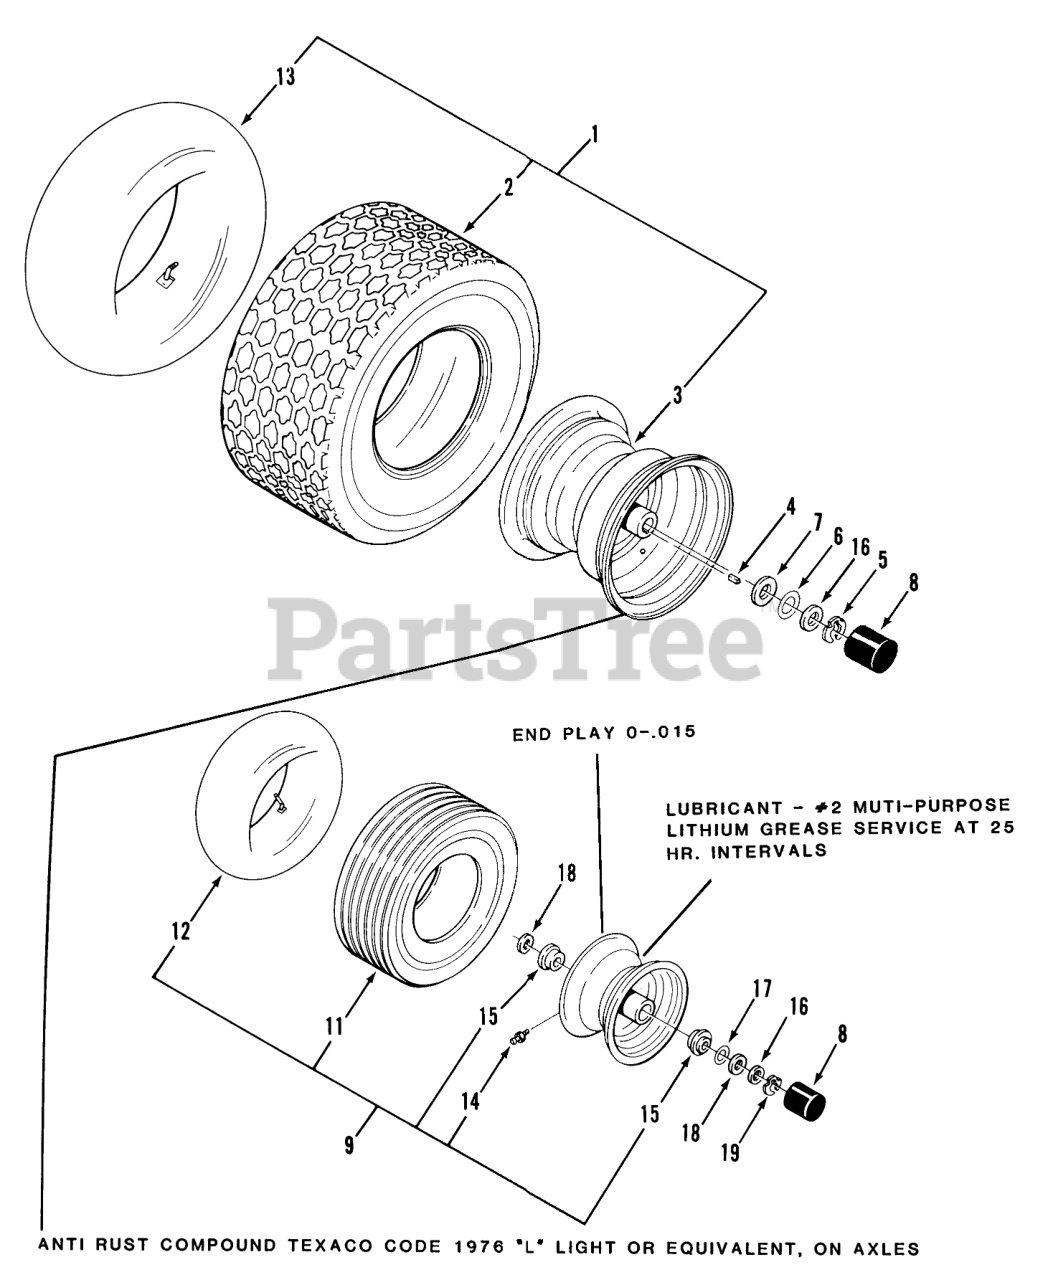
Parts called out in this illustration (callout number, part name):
1	Rear Wheel Assembly 18 x 8.50 x 8
2	Rear Tire 18 x 9.50-8
3	Rear Wheel
4	Key
5	Retainer
6	Washer
8	HUB CAP-FLAT BLACK
9	Front Wheel Assembly 11 x 4.00-5
10	WHEEL-ASSEMBLY
11	Front Tire 11 x 4.00-5
12	TUBE-TIRE 11X4.00-5
13	TUBE-TIRE
14	Zerk
15	BEARING-WHEEL
16	WASHER-FLAT
17	WASHER-SHIM
18	WASHER
19	KLIP-RING .75"
